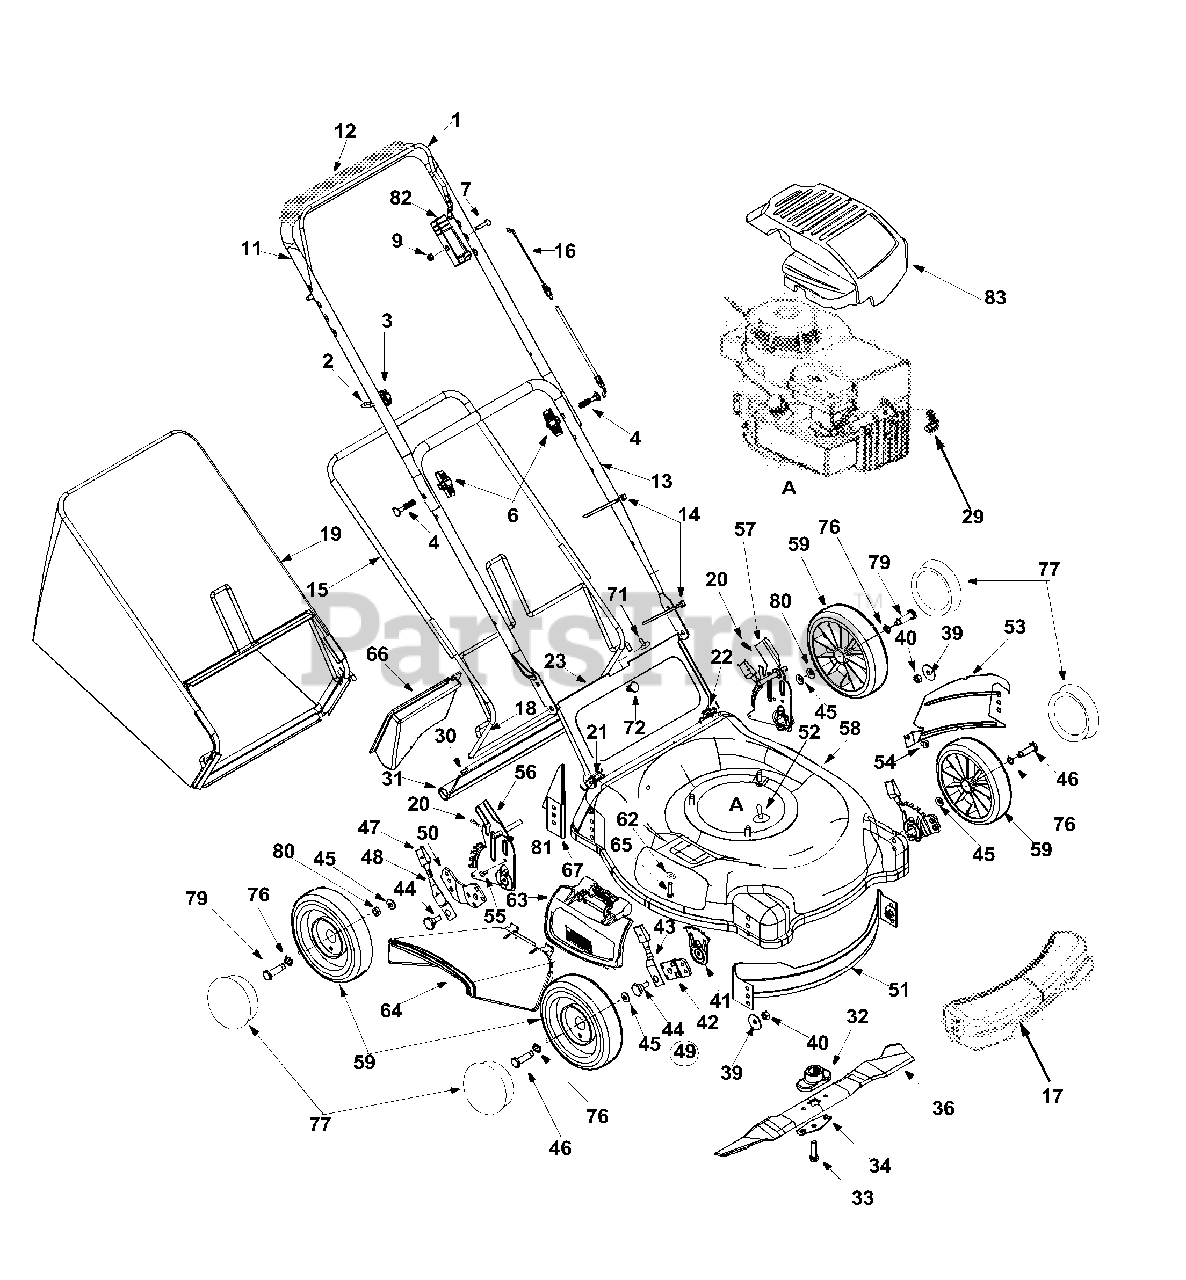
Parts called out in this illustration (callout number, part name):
1	Control Handle Assembly
3	Handle Knob 1/4-20 Thd.
4	Carriage Bolt 5/16-18 x 2" Lg.
7	Oval C-Sunk Mach. Scr.
9	Hex L-Nut 1/4-20 Thd.
14	Cable Tie
16	Control Cable - 43"
17	Front Cover: Gray
20	Int. Cotter Pin 5/16" Dia.
21	Door Spring - R.H.
22	Door Spring - L.H.
30	Wire Rod
31	Rear Flap
32	Blade Adapter
33	Hex Bolt 3/8-24 x 1.5" Lg.
34	Blade Bell Support
36	21" Mulching Blade
39	Bell-Wash. .39" I.D. x 1.38"
40	Hex Nut 3/8-16 Thd.*
41	Height Adj. Plate
43	Front Spring Lever Ass'y. w/Knob
44	Shld. Bolt .5" Dia. x .357"
45	Bell-Wash. .38" I.D. x .88" O.D.
46	Front Axle Bolt
47	Spring Lever Knob
48	Rear Spring Lever
49	Height Adj. Assy. Comp. - RH
50	Pivot Bar R.H.
54	Torx Mach AB-Tap Scr. 1/4 x.62"
55	Hex Ind Wash. Scr. 1/4-14:.625
56	Handle Brkt. Ass'y.-RH
57	Handle Brkt. Ass'y.-LH
62	Bell-Washer 1/4" I.D.
63	Hinged Mulching Plug
64	Chute Deflector: Side Discharge
65	Hex Hd Self-Tp Scr. 1/4-20 x .5" L.
66	Mulching Baffle Plug
71	Truss Scr. #10-24 x .38" Lg.
76	Wave Washer
77	Hub Cap - Rad. Spoke - Grey
79	Rear Axle Bolt
80	Spacer
81	Weld Pin
82	Control Housing w/o Lever
83	Engine Shroud: Oyster Gray
